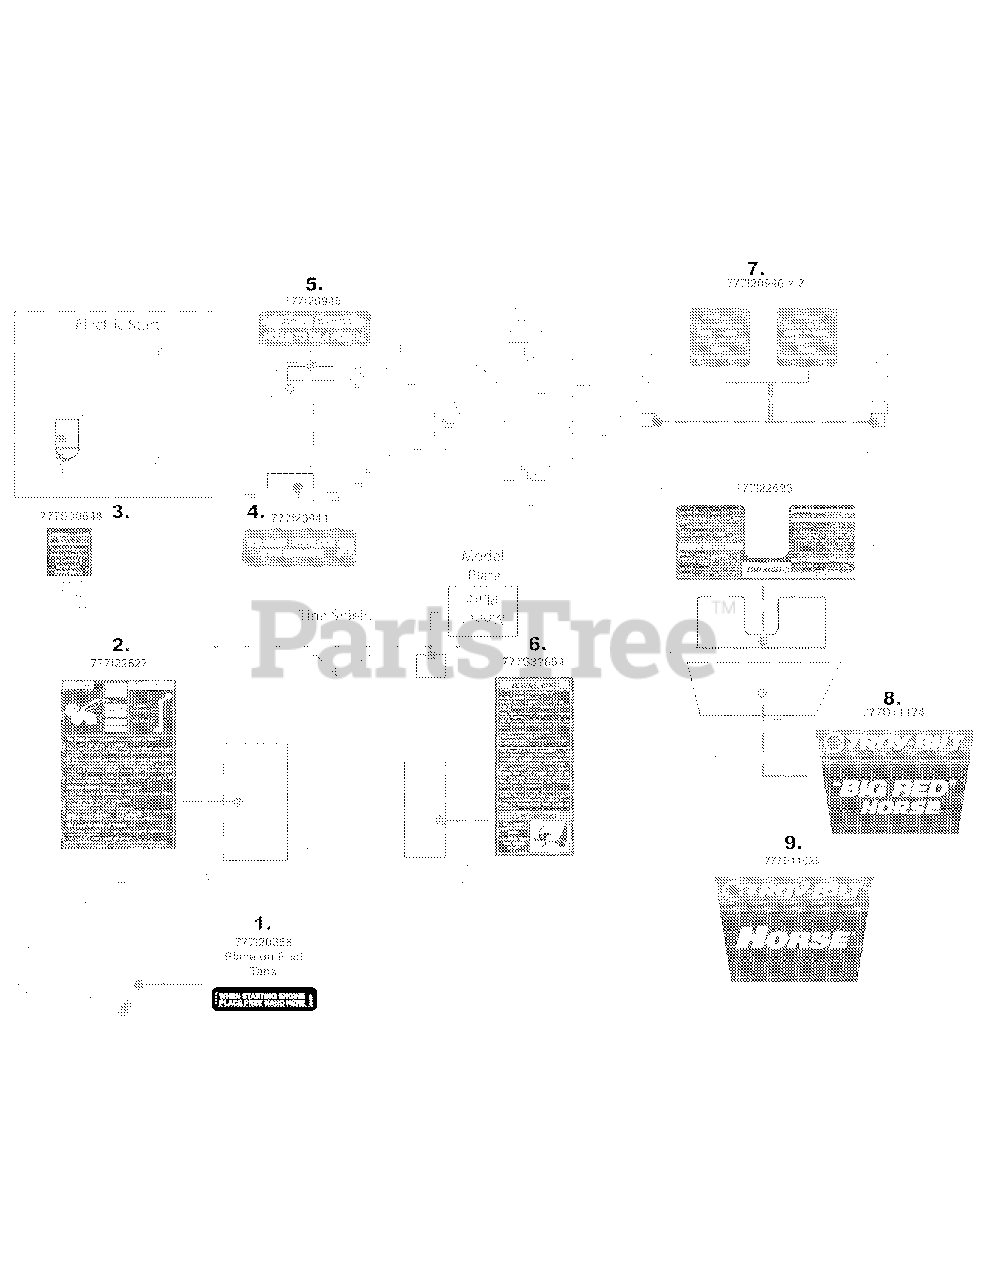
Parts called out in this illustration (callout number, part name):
1	LABEL-PLACE HAND HERE
2	LABEL:TILLER SHIELD 680
3	LABEL-ENGINE IGNIT
4	LABEL-FORWARD INTR
5	LABEL-TINES/PTO CLUTCH
6	LABEL:TILLER/680 TINE SHIELD
7	LABEL-FORWARD INTRLK
8	LABEL-TILLER HANDLE BIG RED
9	LABEL-TILLER HANDLE PANEL:HORSE
